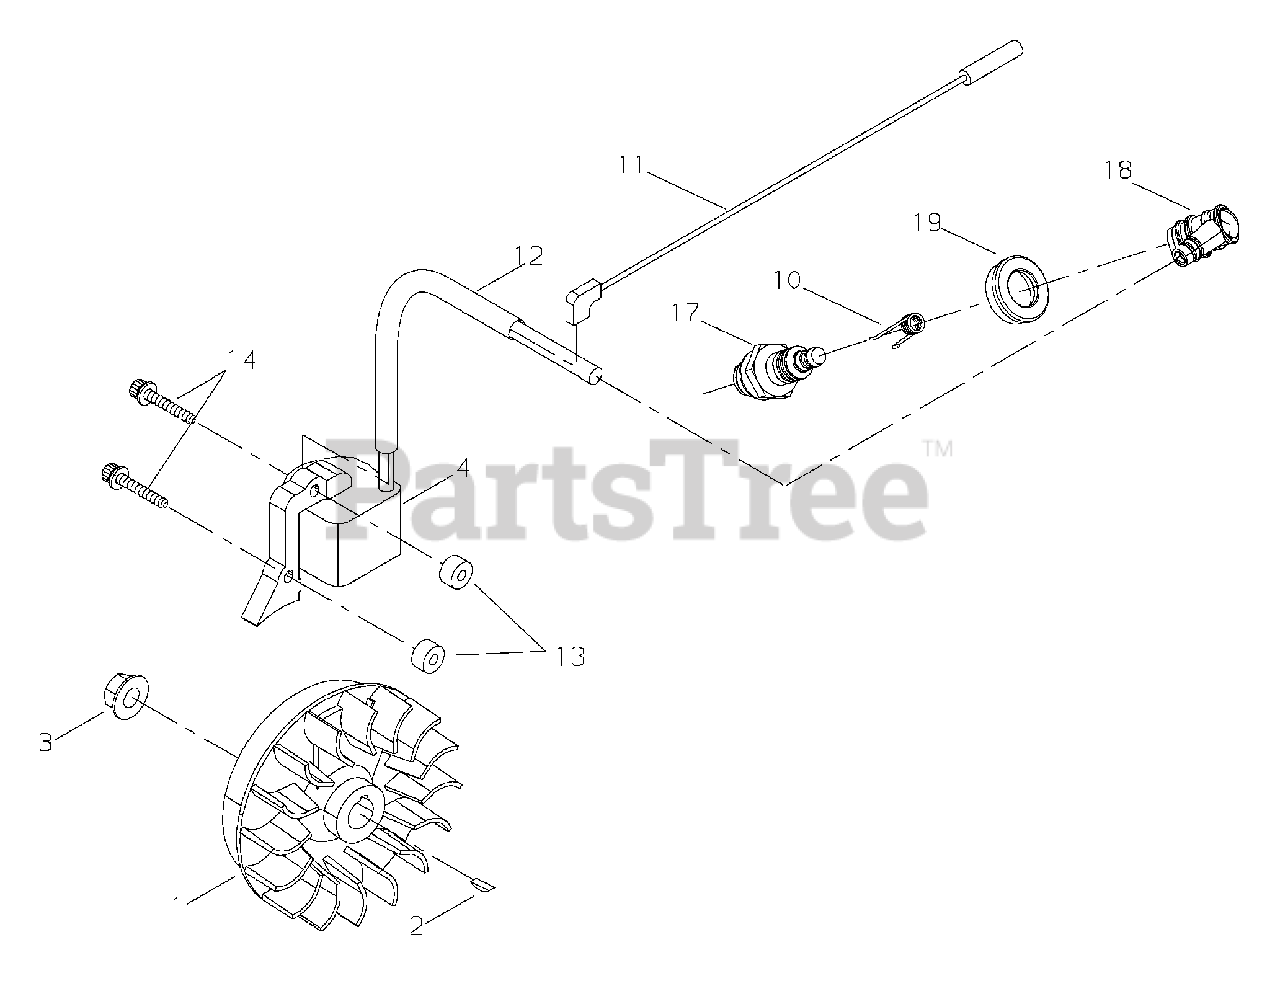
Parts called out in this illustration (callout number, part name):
1	FLYWHEEL
2	KEY - 3X10
3	NUT - 8
4	COIL, IGNITION
10	TERMINAL, SPARK PLUG CAP
11	LEAD - IGNITION
12	TUBE
13	INSULATOR
14	SCREW - 4X20
17	SPARK PLUG -- BPMR-6A
18	CAP, SPARK PLUG
19	SEAL, DUST
